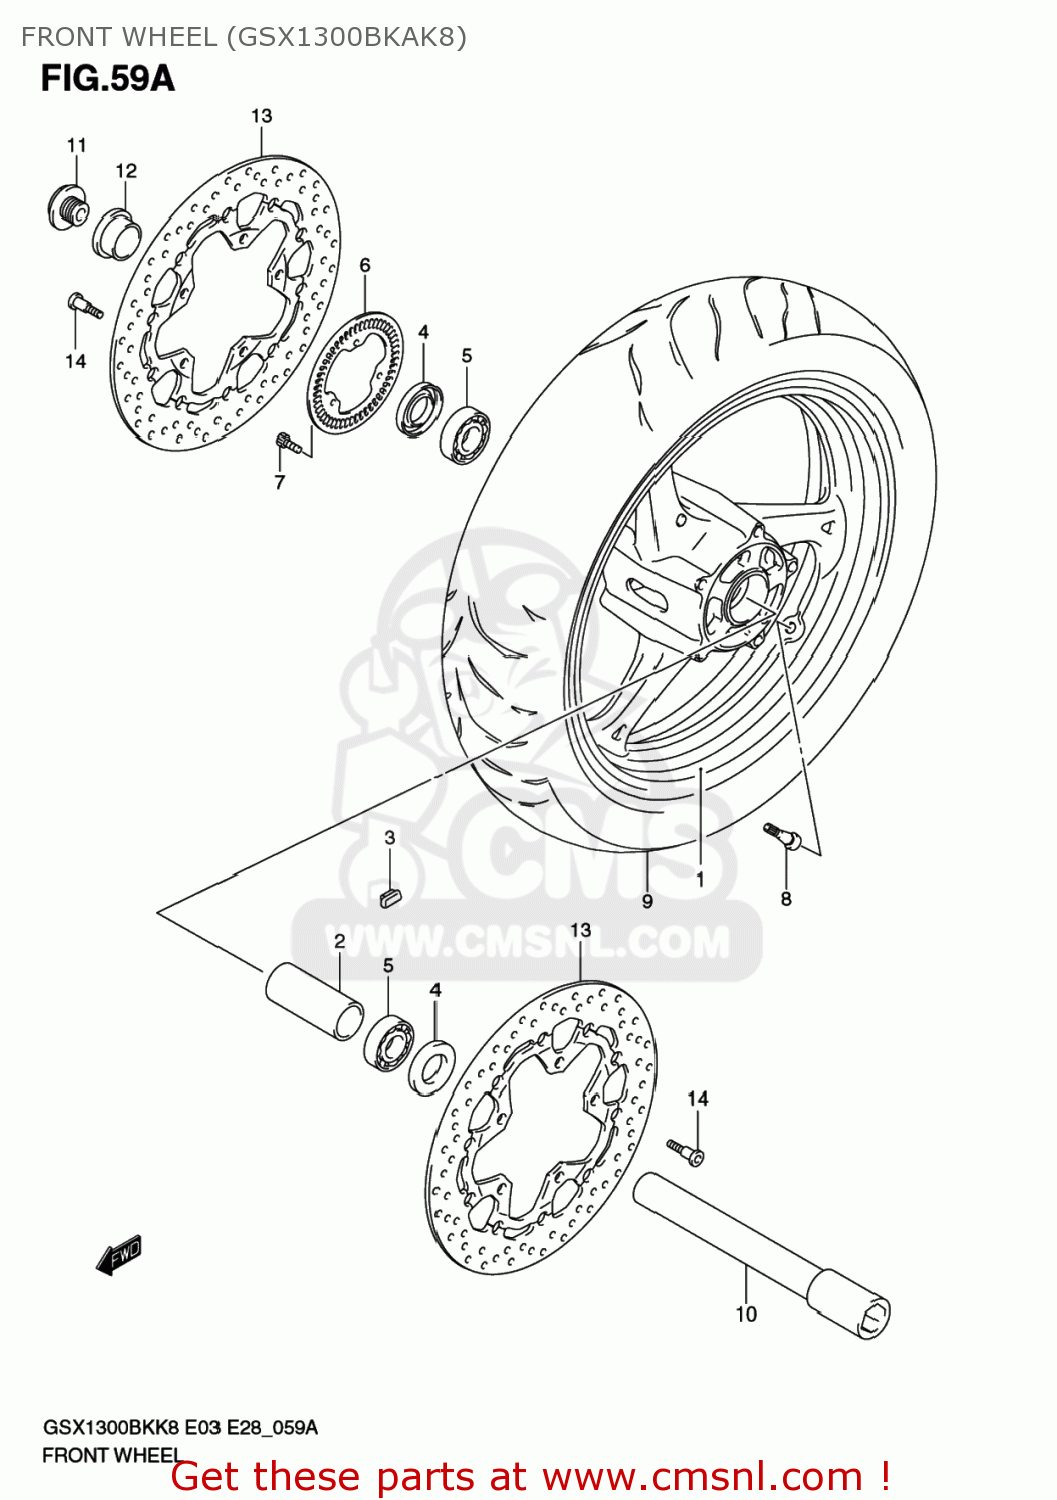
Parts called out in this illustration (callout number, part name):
1	WHEEL,FR(17M/CXMT3.50)
2	SPACER,FR HUB BEARING
3	BALANCER,WHEEL(10G)
4	SEAL,OIL(32X52X7)
5	BEARING(25X52X15)
6	RING,SPEED SENSOR FR(50T)
7	BOLT
8	VALVE ASSY,WHEEL RIM(TR412)
9	TIRE,FR
10	AXLE,FR
11	BOLT,FRONT AXL
12	SPACER,FRONT A
13	DISC,FRONT BRA
14	BOLT(8X21)
